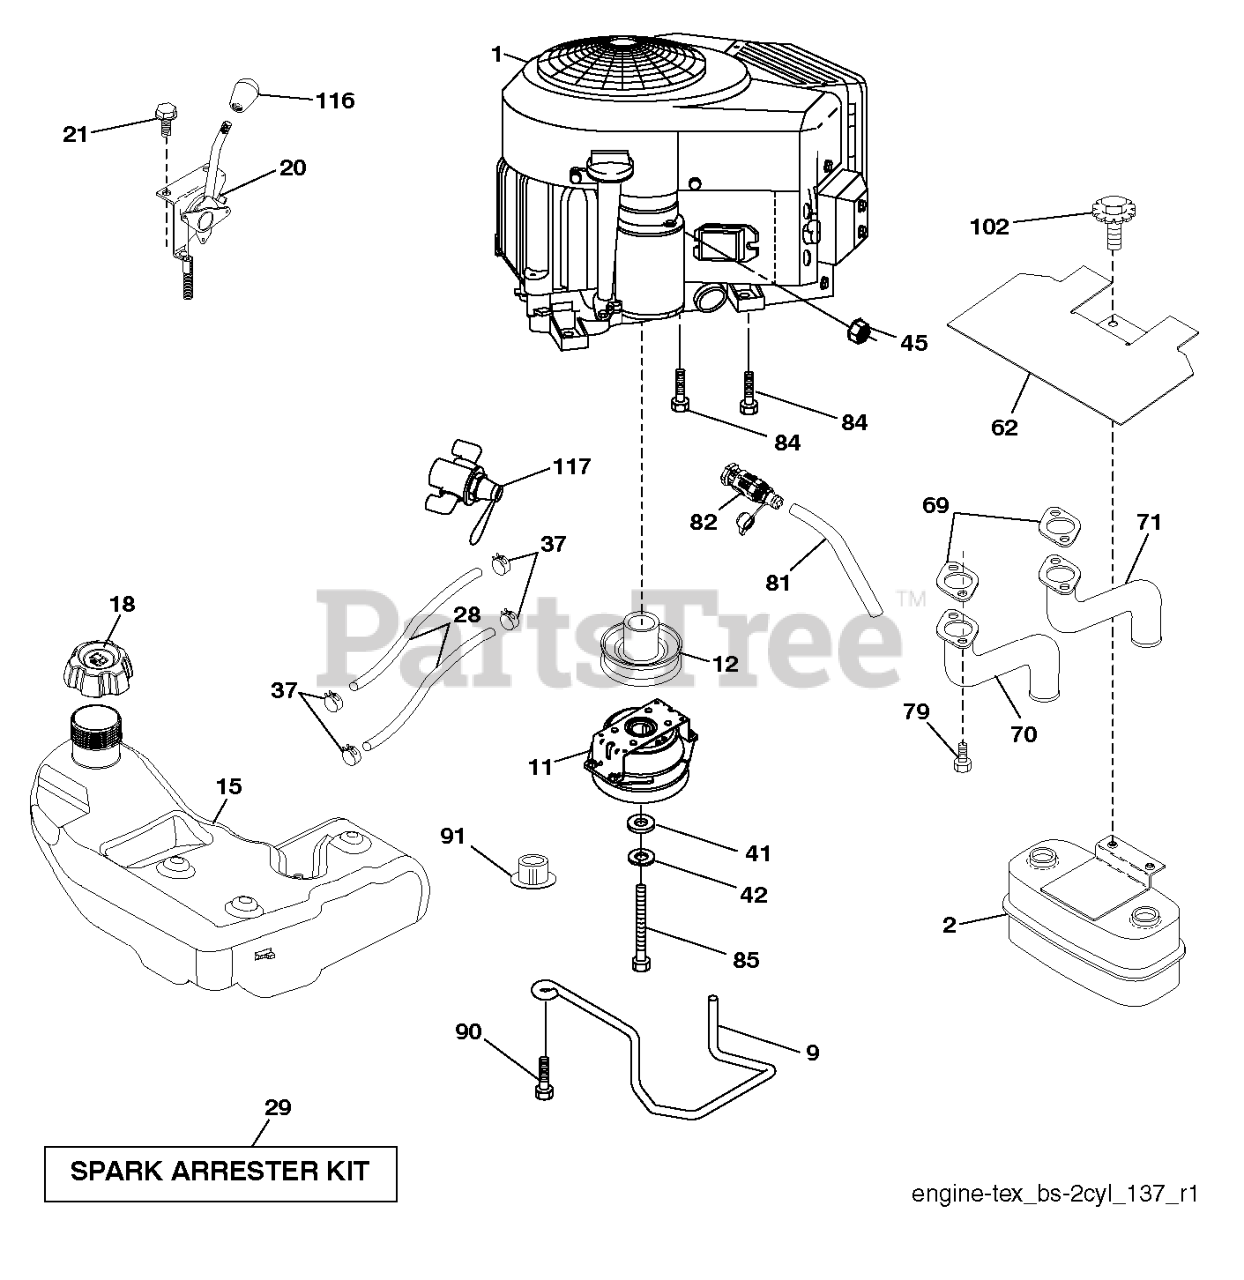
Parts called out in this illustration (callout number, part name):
2	MUFFLER.ASM.TWN.EXTNDED.DFLCTR
9	KEEPER BELT ENGINE
11	CLUTCH.ELECTRIC.LT.48"*
12	PULLEY.ENGINE.TUFFTORQ
18	CAP.ASSY.FUEL.3".N-EPA.GRY.498
20	CONTROL.THROTTLE/CHOKE.PRO.45
21	SCREW.#10 X 0.750.BOS
28	REPL BY 532 00 85-43
29	KIT.SPARK ARRESTOR 794945 B&S
37	HOSE CLAMP
42	LOCKWASHER
45	NUT
62	SHIELD.HEAT.MUFFLER
69	GASKET.MUFFLER
70	EXHAUST.TUBE.LH.BS/TWIN
71	EXHAUST.TUBE.RH.B&S.TWIN.INTEK
79	SCREW.SOCKET.HEAD.5/16-18
84	SCREW.3/8-16
85	BOLT HEX 7/16-20X4-1/4"
87	BOLT.5/16-18UNCX3/4 W/SEMS.BLK
90	SCREW 3/8-16X1
91	BUSHING.1.375OD
116	KNOB - SHIFT
117	VALVE FUEL RESERVE
